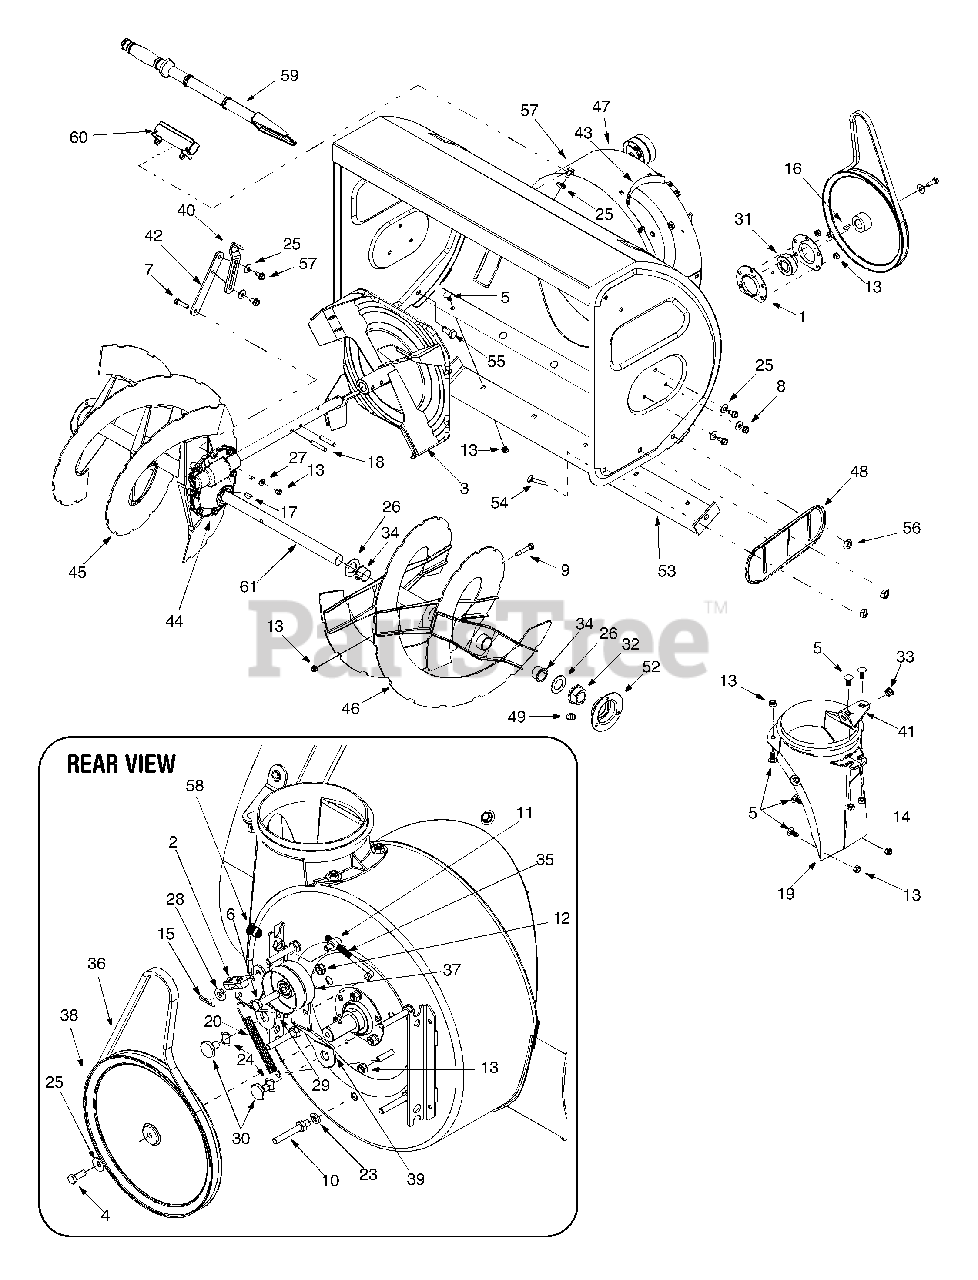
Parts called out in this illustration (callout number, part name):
1	Bearing Housing
2	Auger Brake Bracket Assembly
5	Carriage Bolt 5/16-18 x .750"
6	Hex Screw, Special 3/8-24 x 1.5"
7	Hex Screw 5/16-18 x 1.25"
8	Self-Tapp. Screw 5/16-12 x.750"
9	Shear Bolt 5/16-18 x 1.75"
11	Ferrule
12	Jam Nut 3/8-24
13	Flange Lock Nut, 5/16-18
15	Hairpin Clip
18	Spiral Pin
19	Chute Adapter
20	Extension Spring
23	Lock Washer
24	Wave Washer
25	Beleville Washer
26	Flat Washer
27	Spring Washer
28	Flat Washer
30	Shoulder Screw
31	Self-Aligning Bearing
32	Flange Bearing w/Flats
33	Plastic Bushing
34	Flange Bushing
35	Auger Idler Rod
36	V-Belt
37	Flat Idler
49	Lube Fitting
50	Screw, 5/16-18 x.75"
54	Carriage Screw
55	Carriage Bolt
56	Flange Lock Nut, 3/8-16
57	Screw, 5/16-18 x.75
58	Insert Nut, 3/8-16
59	Clean-out Tool
60	Clean-out Tool Mount
61	Spiral Axle
